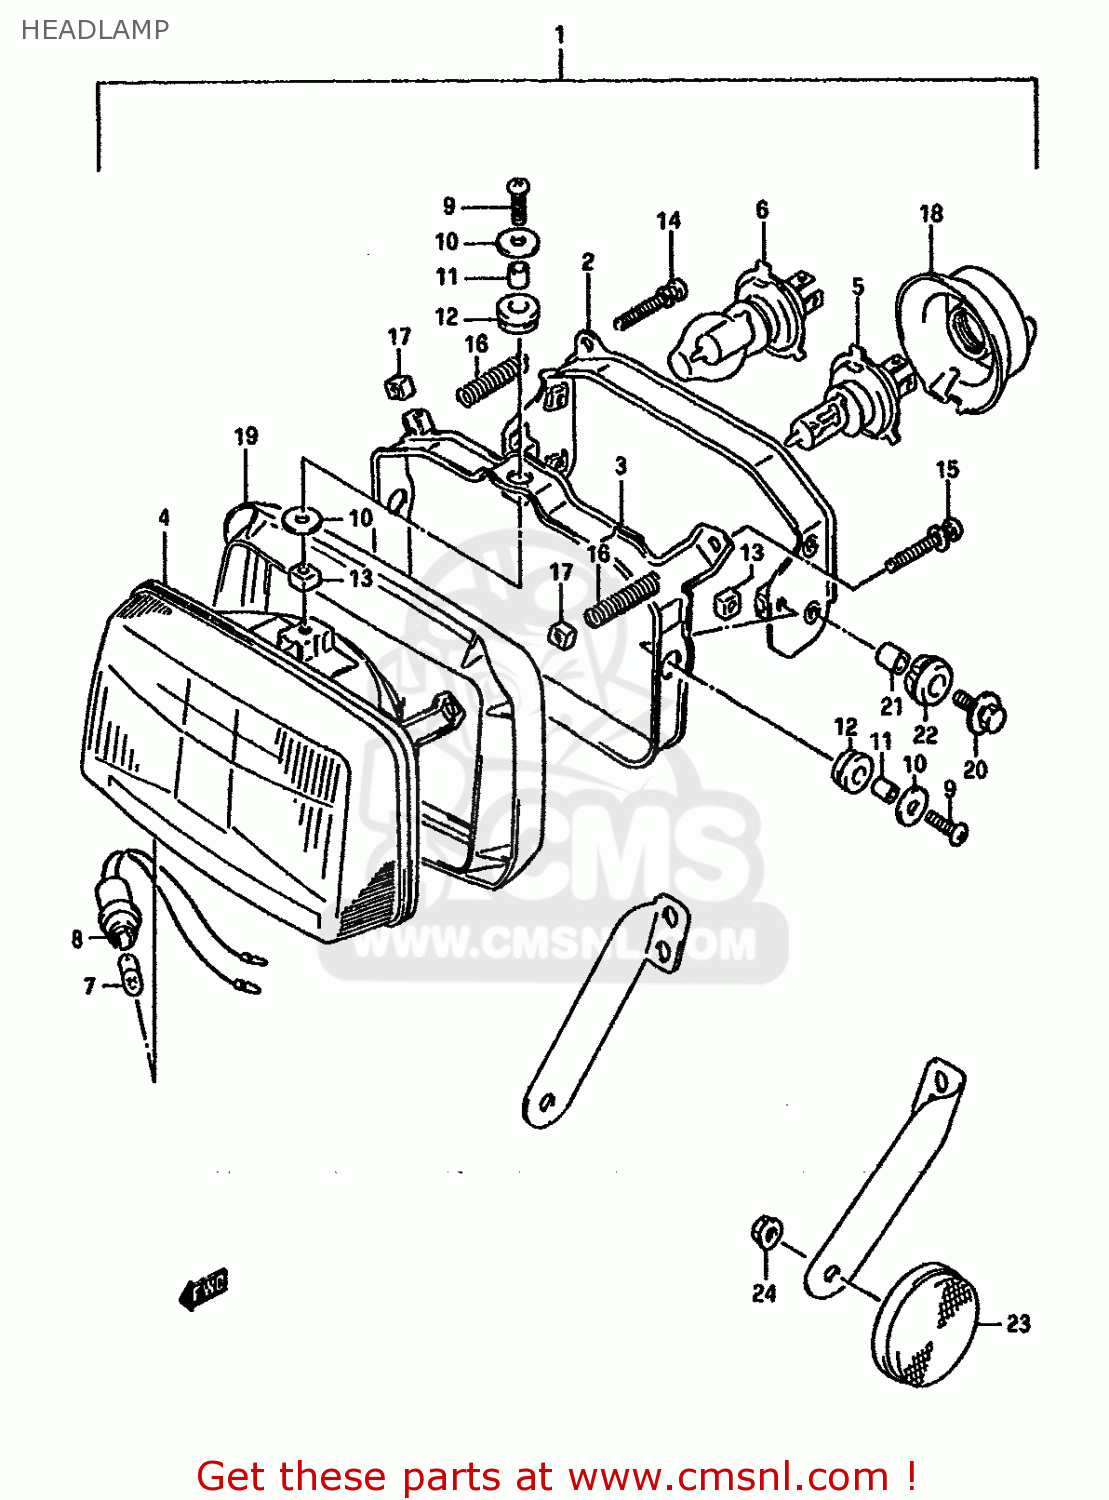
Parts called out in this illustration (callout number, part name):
1	HEADLAMP ASSY
2	HOUSING
3	RING
4	LAMP,UNIT
5	BULB(12V60/55W,H4)
6	BULB (12V, 60/55W, H4)
7	BULB(12V4W)
8	SOCKET
9	SCREW (5X18)
10	WASHER
11	SPACER
12	CUSHION
13	NUT
14	SCREW
15	SCREW
16	SPRING
17	NUT
18	COVER,SOCKET
19	SHADE
20	BOLT 6X20
21	SPACER (6.8X10X10)
22	CUSHION
23	REFLECTOR,REFLEX FR
24	NUT 5MM
